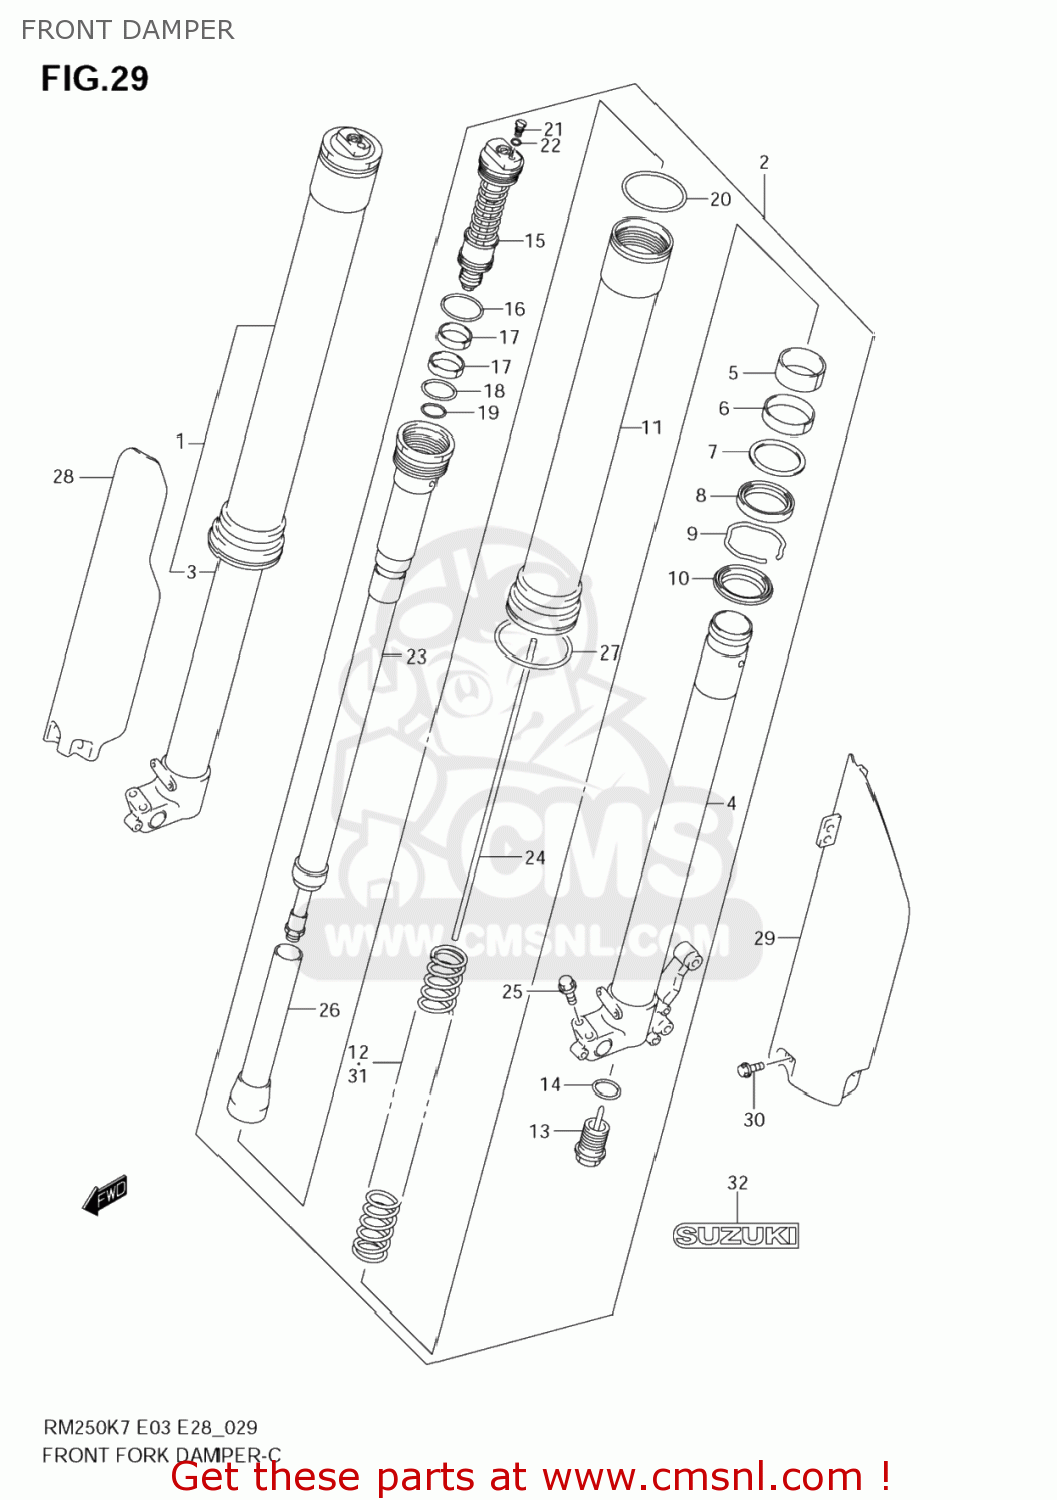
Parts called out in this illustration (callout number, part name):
1	DAMPER ASSY,FR FORK,R
2	DAMPER ASSY,FR FORK,L
3	TUBE,INNER,R
4	TUBE,INNER,L
5	BUSH,SLIDE
6	BUSH,GUIDE
7	SPACER,SEAL
8	SEAL,OIL
9	RING,OIL SEAL STOPPER
10	SEAL,DUST
11	TUBE,OUTER
12	SPRING,FR(K=0.44)
13	BOLT,CTR
14	O RING
15	BOLT,FORK
16	O RING
17	BUSH,FORK BOLT SLIDE
18	O RING
19	O RING
20	O RING
21	BOLT,PLUG
22	O RING,PLUG
23	ROD,DAMPER
24	ROD,PUSH
25	BOLT
26	COLLAR,SPRING
27	STOPPER,RING
28	PROTECTOR,FR FORK,R
29	PROTECTOR,FR FORK,L
30	BOLT(6X10)
31	SPRING,FR(HARD,K=0.46)
32	EMBLEM,SUZUKI
